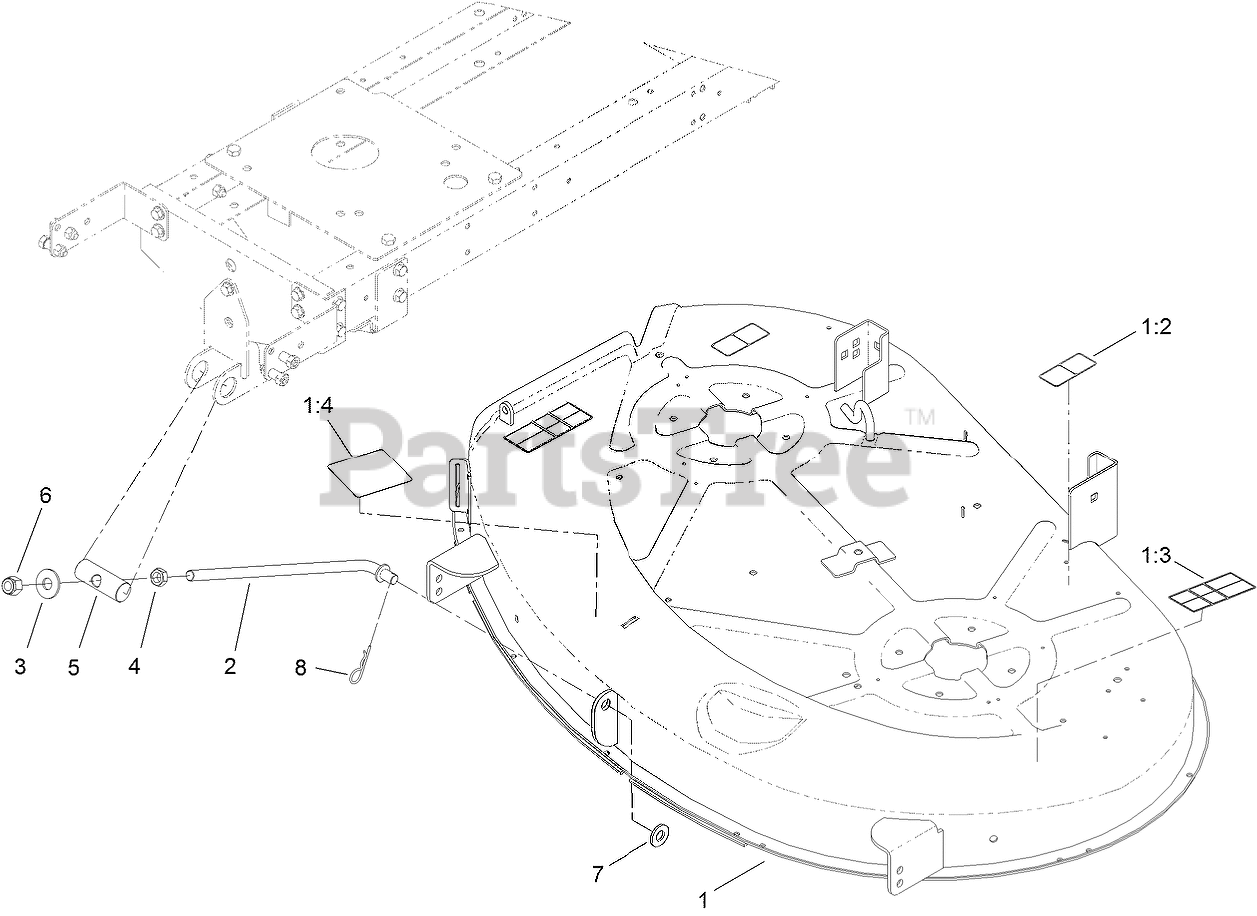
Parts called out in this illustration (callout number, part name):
1	42 INCH DECK ASM
1:2	DECAL-WARNING
1:3	DECAL-WARNING
1:4	DECAL-GUIDE, BELT
2	ROD-PIVOT
3	WASHER-FLAT
4	NUT-JAM
5	PIN-PIVOT
6	NUT-HEX
7	WASHER-THRUST
8	PIN-HAIR
